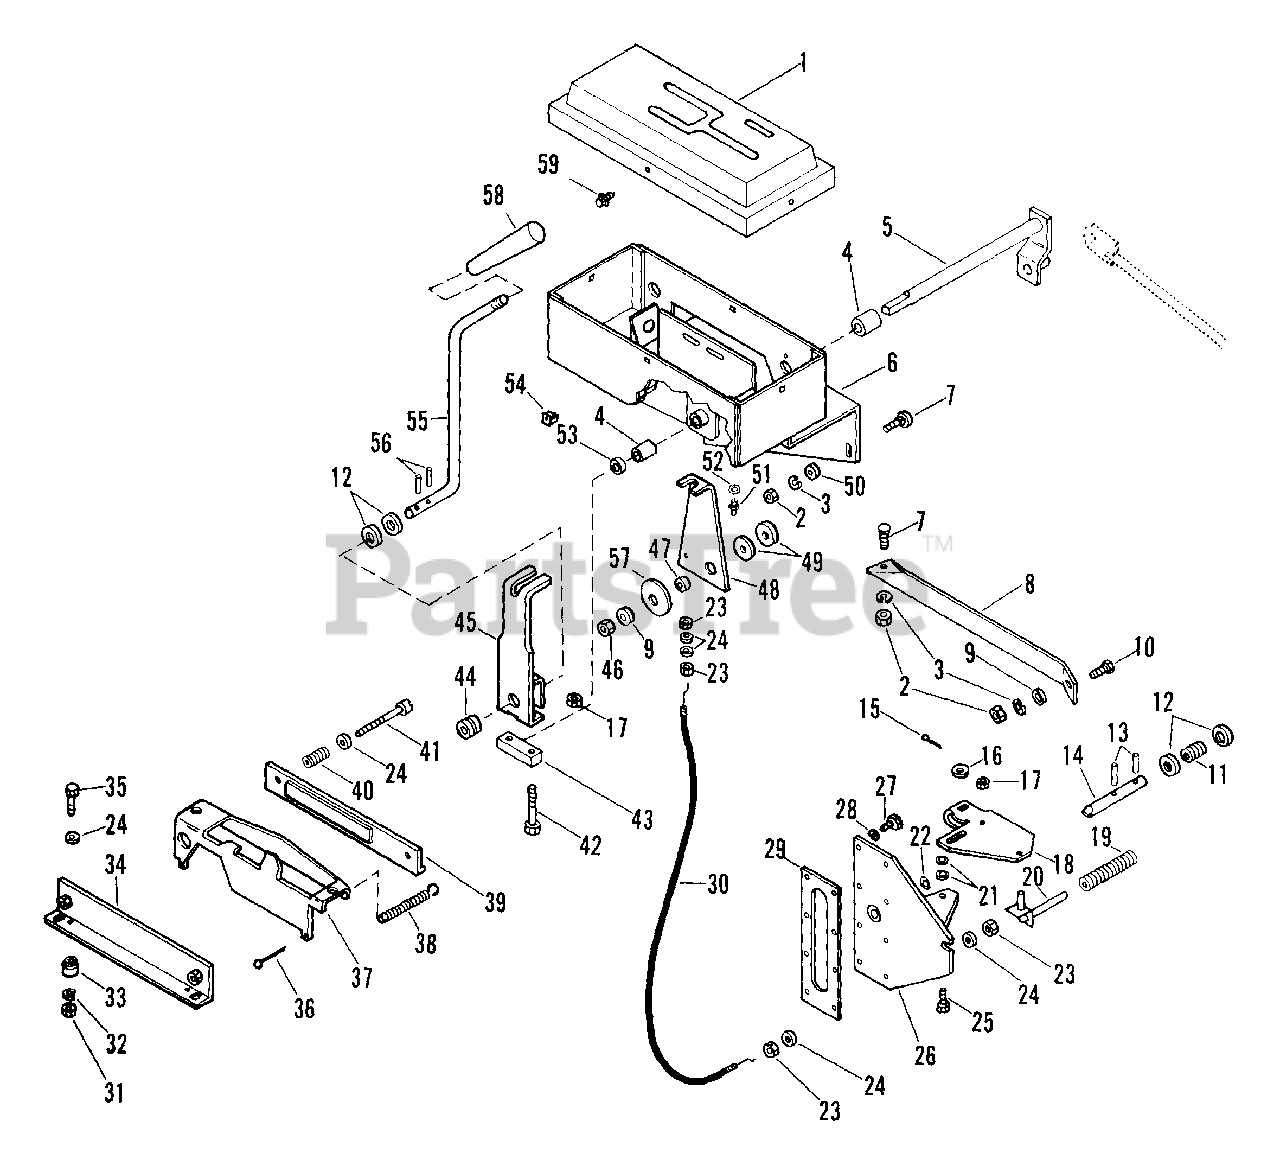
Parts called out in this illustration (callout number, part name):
1	CONTROL CONSOLE
2	NUT-HEX .375-16
3	WSHR-LK .375X.094 MED PL
4	BSHG-SLV .625X.750X1.000
5	SHIFT SHAFT
6	CONTROL BOX
7	BLT-RDHDSQSHNK .38-16X1.00 PL
9	WSHR-FL-STL.406X.812X.065PL
10	BLT-HEX .38-16X.75 PL GR2
11	SG-COMP .072X.687X.75
12	WSHR-FL-STL .531X1.062X.095 PL
13	PIN-ROLL .188X1.25
14	LOCK PIN
15	PIN-COTR .12X.75 PL
16	WSHR-FL-STL .344X1.375X.075 PL
17	NUT-LK-TOP .312-18 GR C PL
18	LOCK PIVOT PLATE
19	SG-COMP .092X.77X3.13 WLD 36
20	PIVOT PIN
21	WSHR-FL-STL.344X.688X.065PL
22	O-RING .500X.629X.070
23	NUT-JAM .312-24 PL
24	WSHR-FL-STL .323X.625X.062 PL
25	BLT-HEX .31-18X.75 PL GR5
26	LOCK PIN GUIDE
27	TAPTITE M5-0.8X16MM H-FL-PL
28	WSHR-LK-EXT 12X.025 PL
29	GASKET
31	NUT-HEX .312-18
32	WSHR-LK .312X.097 PL HVY
33	SPACER .344X.750X.625X.500
34	R.H. FRICTION BRAKE
35	BLT-HEX .31-18X1.25 PL GR2
36	PIN COTR .09X.50 PL
37	SHIFT LOCK
38	SG-TENS .035X.45X2.75 WLD 3.5
39	L. H. FRICTION BRAKE
40	SG-COMP .093X.59X1.50
41	SCR-MCH .31-18X2.75 SLRH PL
42	BLT-HEX .31-18X1.50 PL GR5
44	GROMMET .438ID X .688 OD
46	NUT-LK-CTR .375-16 GR A PL
47	BSHG-SLV .377X.624X.235
49	WSHR-FL-STL .438X1.125X.19
50	WSHR-FL-STL .438X1.0X.083 PL
51	SPIN DRIVE ZERK FITTING
52	WSHR-LK .250X.047 LT PL
53	WSHR-FL-STL .630X1.005X.062 PL
54	PLASTIC GROMMET
55	SHIFT ROD
56	PIN-ROLL .188X.88
57	BELLEVILLE WASHER
59	SCR-TAP 10-12X.50 CRPH PL A
